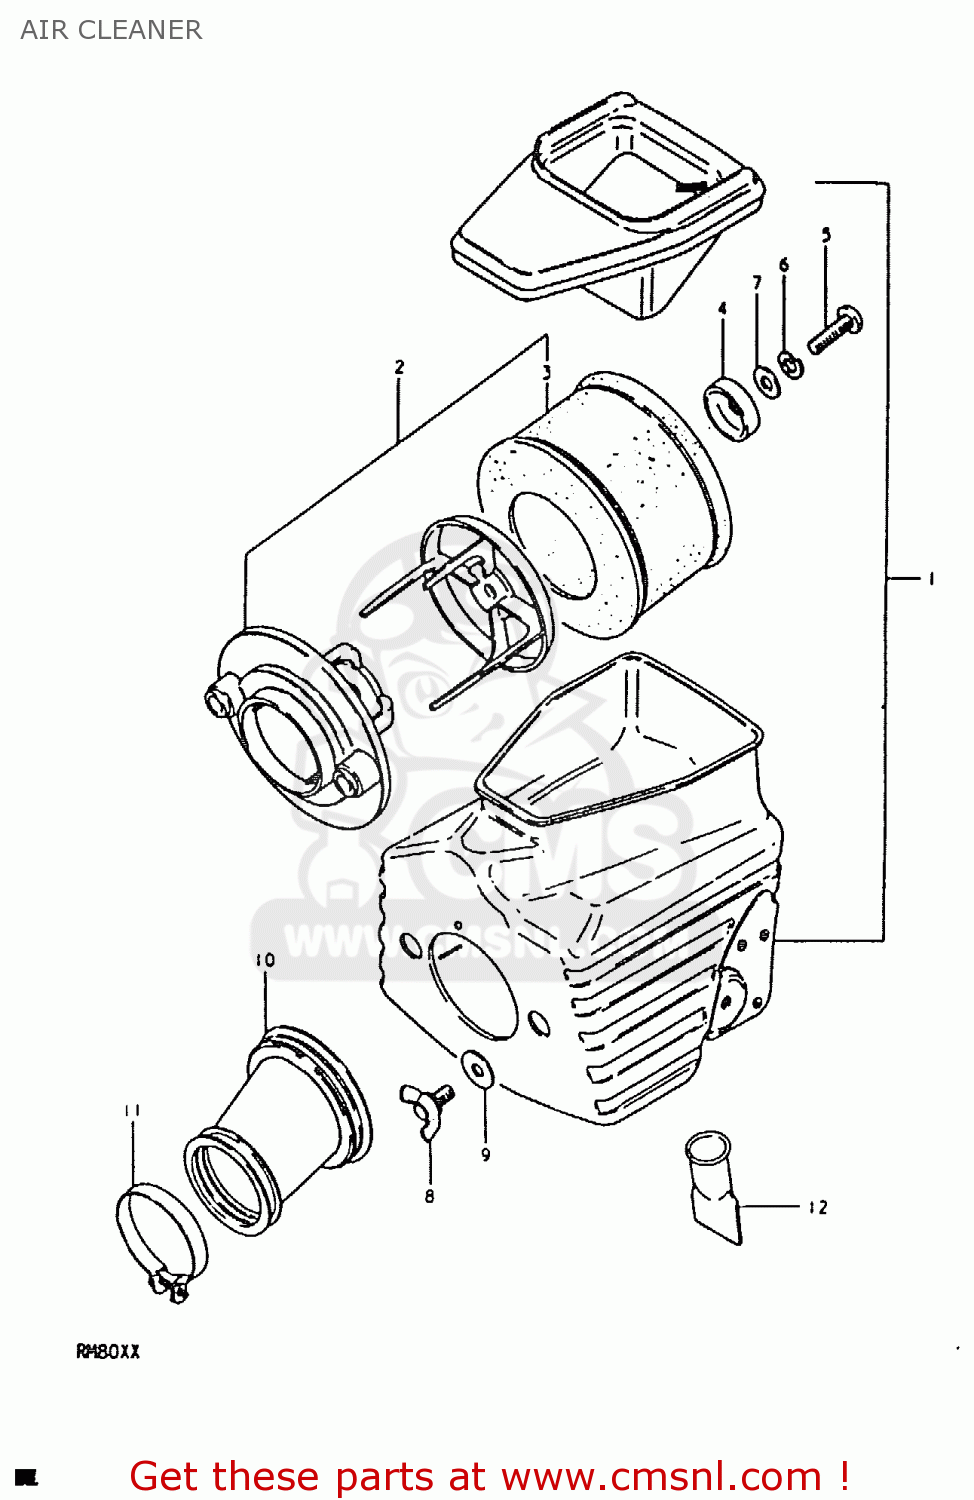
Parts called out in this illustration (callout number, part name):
1	CLEANER ASSEMBLY,AIR
2	FILTER,AIR CLEANER
3	FILTER
4	HOLDER,FILTER
5	SCREW
6	LOCK WASHER
7	WASHER
8	WING BOLT
9	SPACER,AIR CLEANER,REAR
10	HOSE,AIR CLEANER OUTLET
11	CLAMP
12	DRAIN TUBE
